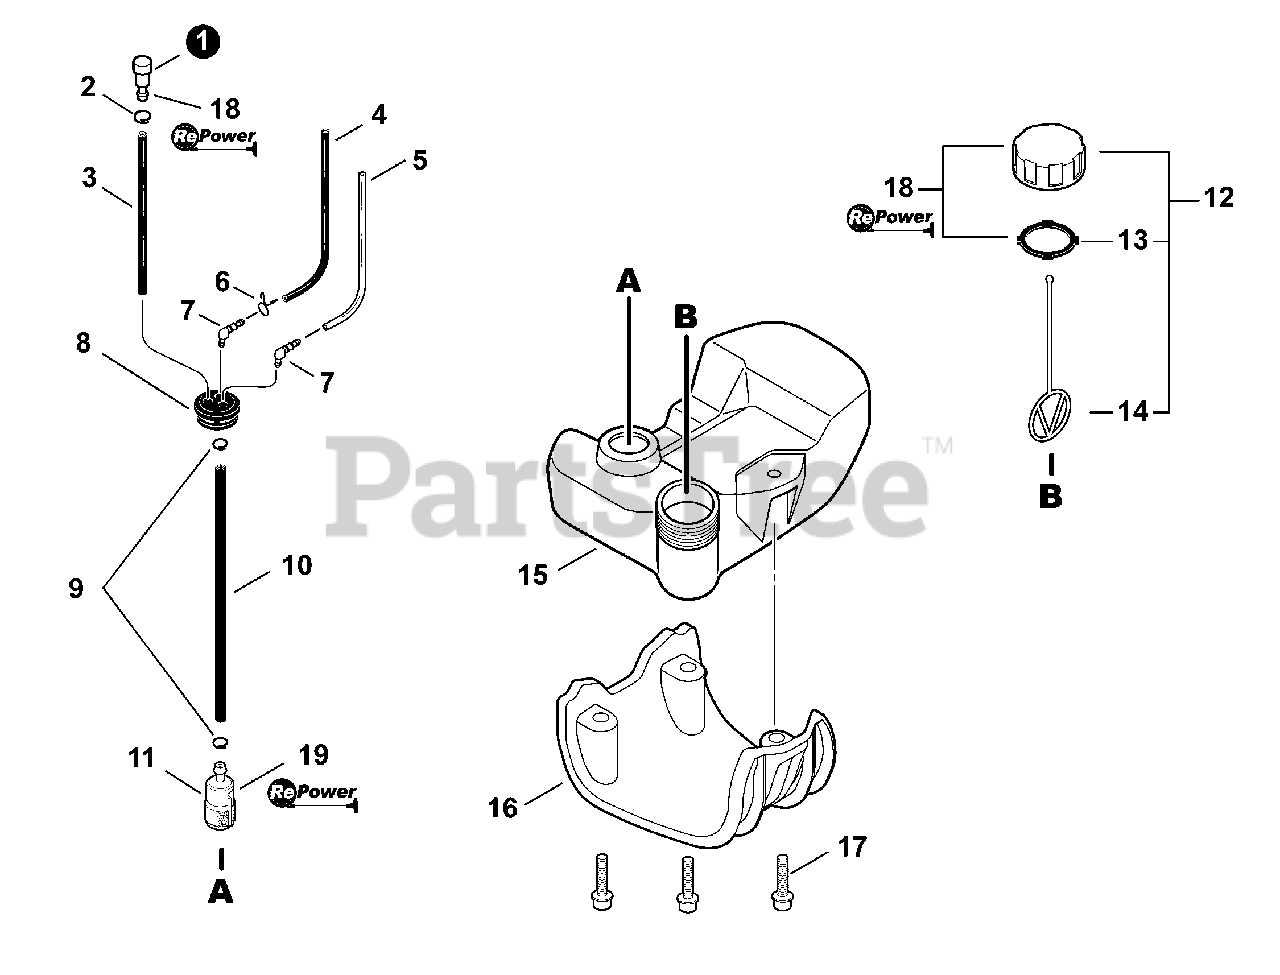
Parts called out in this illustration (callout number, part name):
1	VENT ASSY
2	CLIP 6.5MM
3	PIPE, FUEL 3×6×115 BLACK
4	PIPE, FUEL 3×5×87
5	PIPE, FUEL 3×6×80 CLEAR
6	CLIP, SPRING
7	CONNECTOR, PIPE 5.4
8	GROMMET, FUEL
10	PIPE, FUEL - 3×5×125 - BLACK
11	FILTER, FUEL
12	CAP ASSY, FUEL
13	GASKET, FUEL CAP
14	CONNECTOR, CAP L= 100mm
15	TANK, FUEL
16	GUARD, FUEL TANK
17	BOLT 5×20
18	CAP/VENT KIT - REPOWER
19	TUNE-UP KIT - REPOWER
